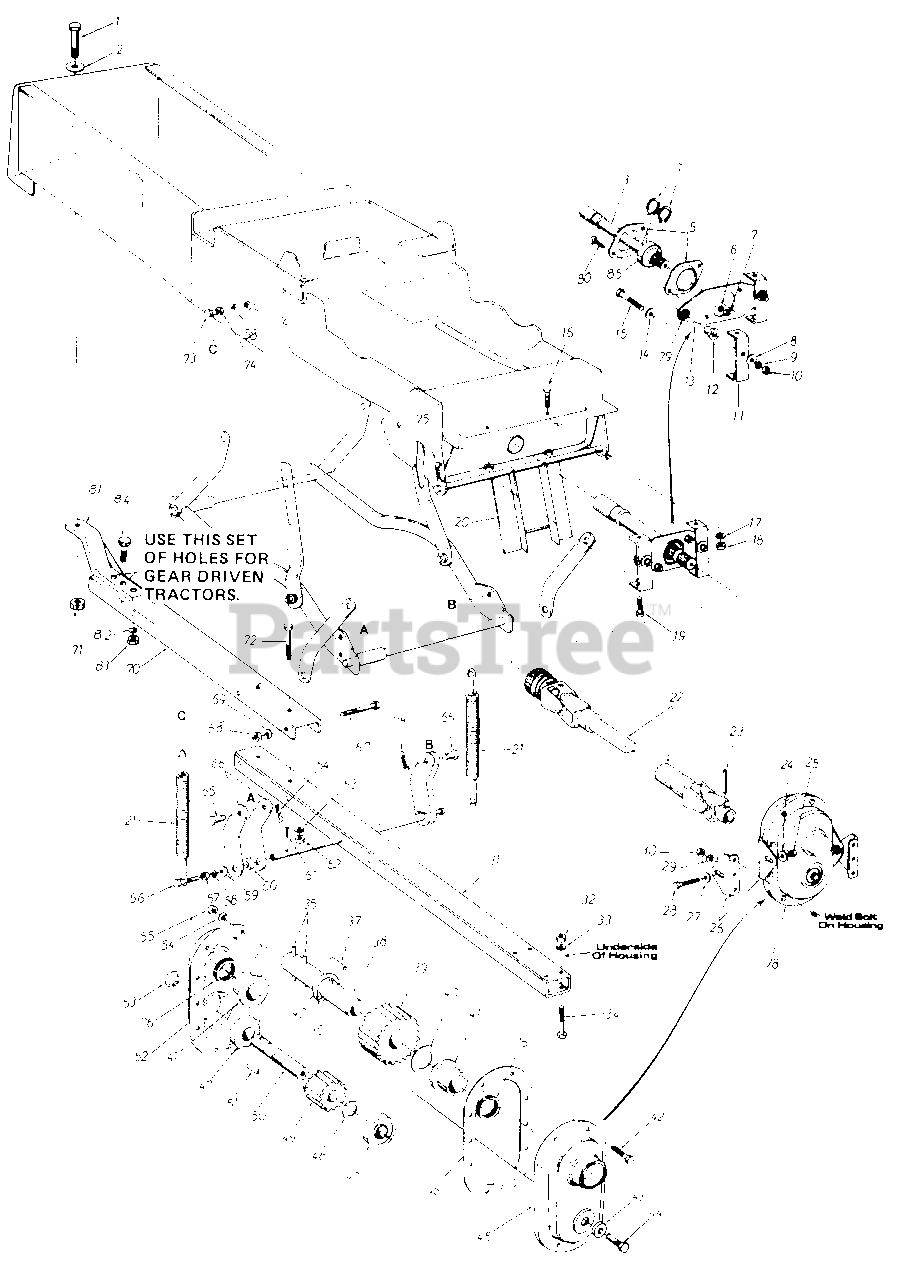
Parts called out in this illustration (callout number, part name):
1	Hex Scr. 5/8-18 x 1.31"Lg.
2	Fl.-Wash. .66" I.D. x 1.25" O.D. x .100
3	P.T.O. Shaft Extension Ass 'y .
4	Retaining Ring 1.00" Dia. Shaft
5	Flangette Bearing
6	L.-Wash-5/16" Scr.*
7	Hex Nut 5/16-18 Thd.*
8	Fl.-Wash. 3/8" I.D. x 1.00" O.D.
9	L.-Wash 3/8" Scr.
10	Hex Nut 3/8-24 Thd.*
11	P.T.O. Bearing Retainer Brkt.
12	Shoulder Spacer
13	P.T.O. Bearing Retainer Plate
14	Fl.-Wash. 3/8" I.D. x 1.00 O.D.
15	Hex Scr. 3/8-24 x 1.50"-Lg.*
16	Hex Scr. 3/8-16 x .75"-Lg.*
17	L.-Wash. 3/8" Scr.*
18	Hex Nut 3/8-16 Thd.*
19	Hex Scr. 3/8-16 x .75" Lg.
20	Guide Bracket Ass'y.
21	Helper Spring .94 O.D. x 7.38" Lg.
22	Universal Drive Shaft Ass'y.
23	Spring Pin Spirol 5/16" x 2.50" Lg.
24	Belleville Wash. .341 I.D. x .88 O.D.
25	Hex Nut 5/16-18 Thd.*
26	Gear Box Support Bracket
27	Belleville Wash. .34 I.D. x .88 O.D.
28	Hex Scr. 5/16-18 x .75" Lg.*
29	L.-Wash. 5/16" Scr.*
30	Hex Nut 5/16-18 Thd.
31	Lift Shaft Ass'y.
32	Hex Ins. Jam L.-Nut 3/8-24 Thd.
33	L.-Wash. 3/8" Scr.
34	Hex Scr. 3/8-24 x 2.75"Lg.
35	Spring Pin Spirol 5/16" Dia. 1.75" Lg.
36	Snap Ring for 1.25" Dia. Shaft
37	Sq. Key 1/4" x 1.00" Lg.
39	28 Teeth Spur Gear
40	Fl.-Wash. 1.31" I.D x 2.00" O.D. x .060
41	Flange Bearing 1.25" I.D. x 1.75" O.D.
42	Hex Screw 1/4-28 x 88 "Lg.
43	Fl. Wash. .40" I.D. x 1.25" O.D. x .160
44	Hex L.-Scr. 3/8-24 x 1.00"Lg.
45	Complete Gear Housing Half-L. H.
47	Ball Bearing 1.00" I.D. x 2.00" O.D.
48	Fl.-Wash. 1.03" I.D. x 1.63" O.D. x .090
49	15 Teeth Spur Gear
51	Woodruff Key 1/4 x 3/4" Dia.
52	Complete Gear Housing Half-R. H.
53	Snap Ring for 1.00" Dia. Shaft
54	L.-Wash. 1/4"Scr.*
55	Hex Nut 1/4-28 Thd.
56	Hex Scr, 5/16-18 x 1.75" Lg.*
57	Hex Nut 5/16-18 Thd.*
58	L.-Wash. 5/16" Scr.*
59	Fl.-Wash. .344 I.D. x 1.12 0 O.D. x .125
60	Spacer .81" I.D. x 1.00" O.D. x .31
61	Cotter Pin 5/32" Dia. x 1.00" Lg.*
62	Hex Ins. Jam L.-Nut 3/8-24 Thd.
63	L.-Wash. 3/8" Scr.*
64	Intern. Cotter Pin 1/2"Dia.
65	Clevis Pin .500" Dia.
66	Lift Bracket
67	Hex Scr. 3/8-24 x 4.50" Lg.*
68	Hex Ins. Jam L.-Nut 3/8-24 Thd.
69	L.-Wash. 3/8" Scr.*
70	Lift Bracket
71	Hex Ins. Jam L.-Nut 5/8-18 0 Thd.
72	Hex Scr. 3/8-24 x 2.75"Lg.*
73	Hex Scr. 5/16-18 x 1.75" Lg. *
74	Hex Nut 5/16-18 Thd.*
75	Intern. Cotter Pin 3/4"Dia.
76	Oil Seal 1.25" I.D. x 1.75" O.D. x .26
78	Gear Box Ass'y. Comp.
79	Rubber Grommet .50" I.D.
80	Carriage Bolt 5/16-18 x .75 Lg.*
83	Hex Nut 1/2-13 Thd.
84	Hex Scr. 1/2-11 3-1/4 Lg.
85	Ball Bearing
